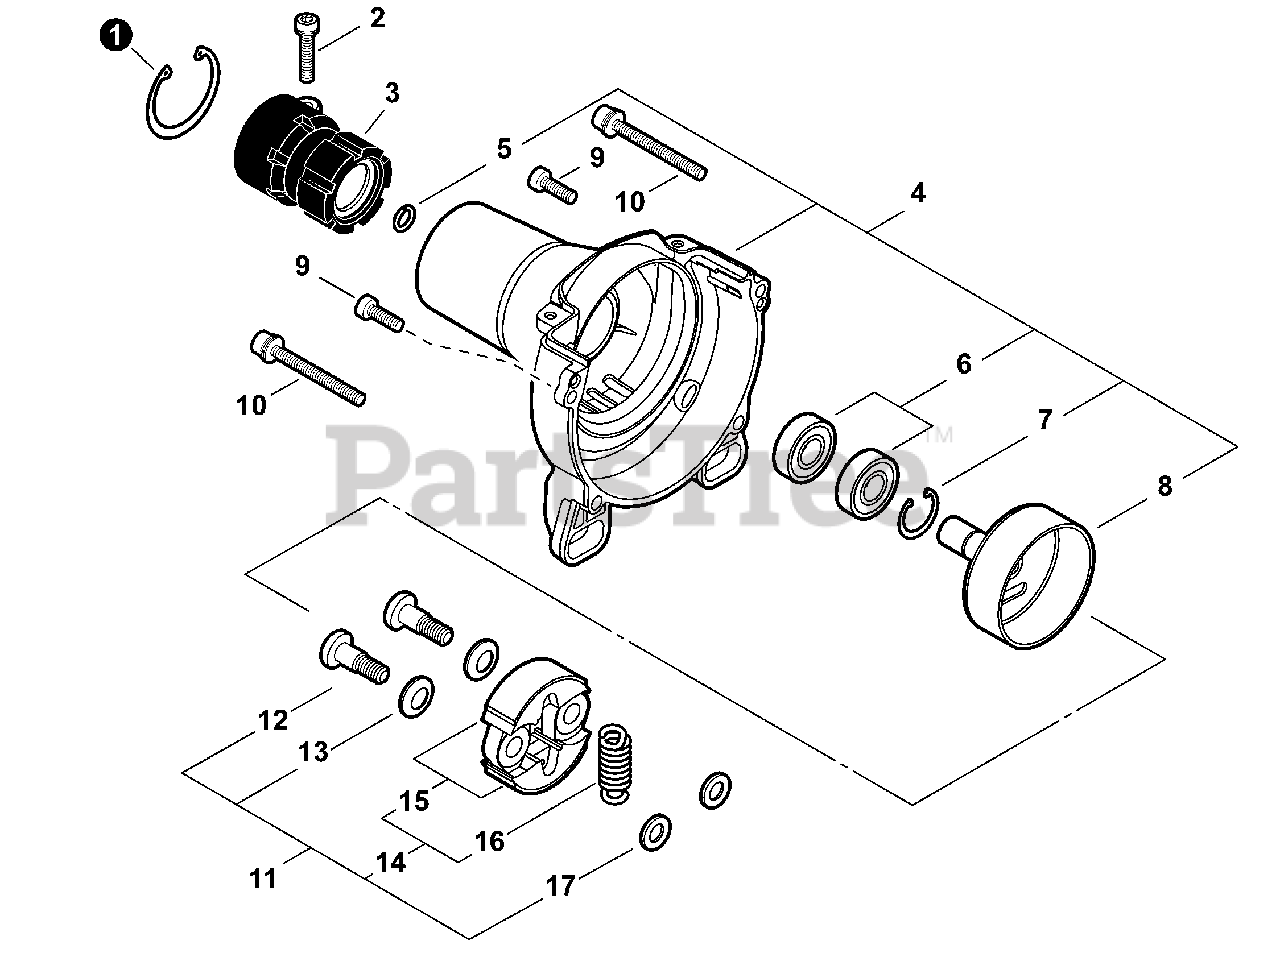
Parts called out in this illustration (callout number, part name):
1	RING, SNAP Ø40
2	BOLT M5×22
3	CUSHION, AV
4	COVER ASSY, FAN
5	RING, SNAP Ø10
6	BEARING, BALL 6000ZZ
7	RING, SNAP 26
8	DRUM, CLUTCH
9	BOLT M5×16
10	BOLT M5×45
11	CLUTCH ASSY
12	BOLT, CLUTCH
13	WASHER, SPRING
14	SHOE ASSY, CLUTCH
15	SHOE, CLUTCH
16	SPRING, CLUTCH
17	WASHER 6 MM
